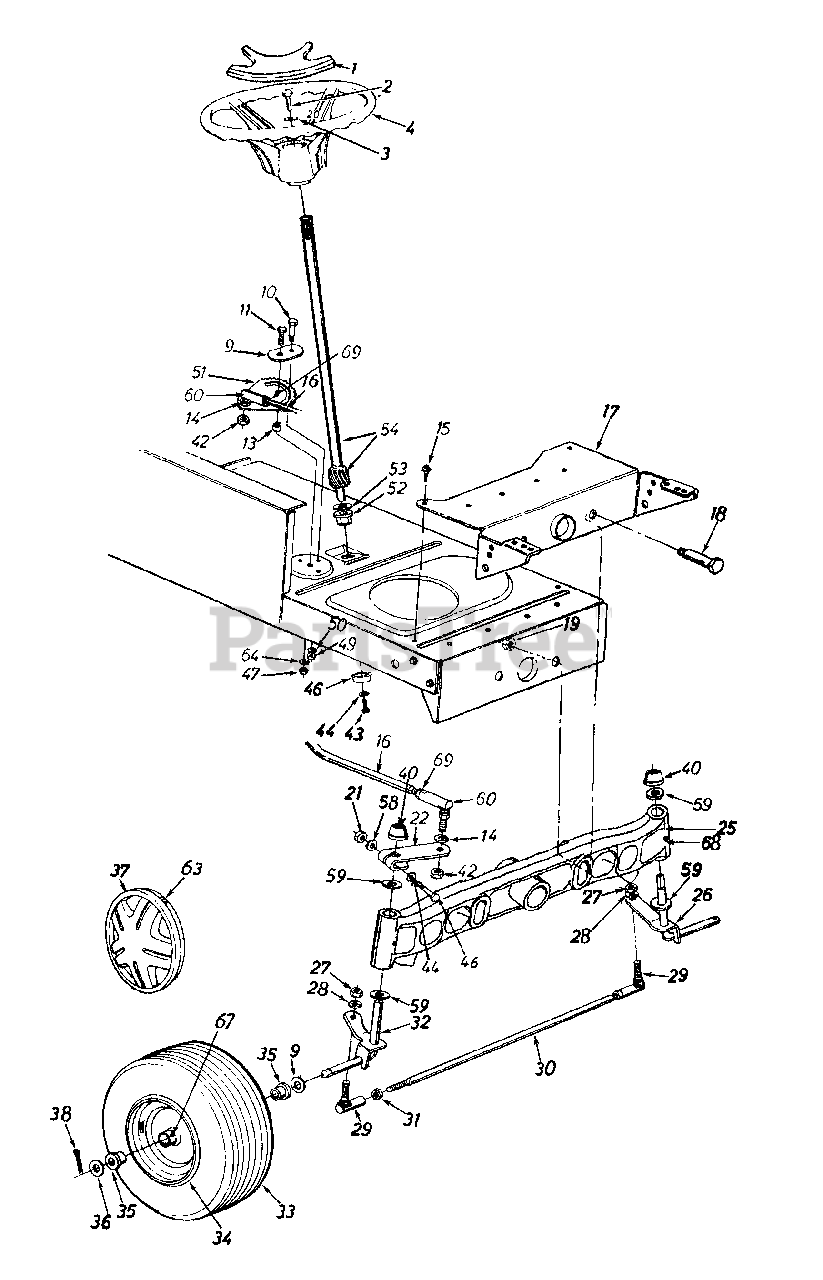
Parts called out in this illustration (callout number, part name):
1	Steering Wheel Cap
2	Hex Bolt 5/16-18 x 1" Lg.
3	Belleville Wash. .345" I.D.
4	Steering Wheel
9	Retainer Plate
10	Shld Bolt .437" Dia. x .35" Lg.-5/16-18
11	Hex Bolt 3/8-24 x 1.0" Lg. (Grade 5)
13	Spacer .380" I.D. x .625" O.D. x .227
14	L-Wash. 3/8" I.D. (H.D.)
15	Hex Wash. Hd. Self-Tap Scr.
16	Steering Drag Link
18	Shld Bolt .498" Dia. x 2.04" Lg.-3/8-16
19	Flanged Hex Nut 3/8-16 Thd.
21	Hex L-Nut 5/16-24 Thd.
22	Steering Arm Front Axle
25	Pivot Bar Ass'y.
26	Front Axle Ass'y.-L.H.
27	Hex Nut 3/8-24 Thd.
28	L-Wash. 3/8" I.D.
29	Ball Joint 3/8-24 Thd.
31	Hex Jam Nut 3/8-24 Thd.
32	Front Axle Ass'y.-R.H.
36	Fl-Wash. .635" I.D. x 1.59" O.D.
37	Hub Cap
38	Cotter Pin 1/8" Dia. x 1.25"
40	Push Cap 5/8" Dia. Rod
42	Hex Jam Nut 3/8-24 Thd.
43	Torx Bolt 5/16-18 x .63" Lg.
44	L-Wash. 5/16" I.D.
46	Cap
47	Hex Cent. L-Nut 3/8-24 Thd.
49	Hex Cent. L-Nut 5/16-18 Thd.
50	L-Wash. 5/16" I.D.
51	Steering Gear Segment
52	Hex. Flg. Brg. 5/8" I.D.
53	Fl-Wash. (Hardened)
54	Steering Shaft
58	Wave-Wash. .32" I.D. x .62" O.D.
59	Fl-Wash. (Hardened)
60	Drag Link Ball Joint 7/16-20 Thd.
63	Spring Clip
64	Bell-Wash. .39" I.D. x 1.38" O.D.
67	Grease Fitting
68	Grease Fitting
69	Hex Jam Nut 7/16-20 Thd.
